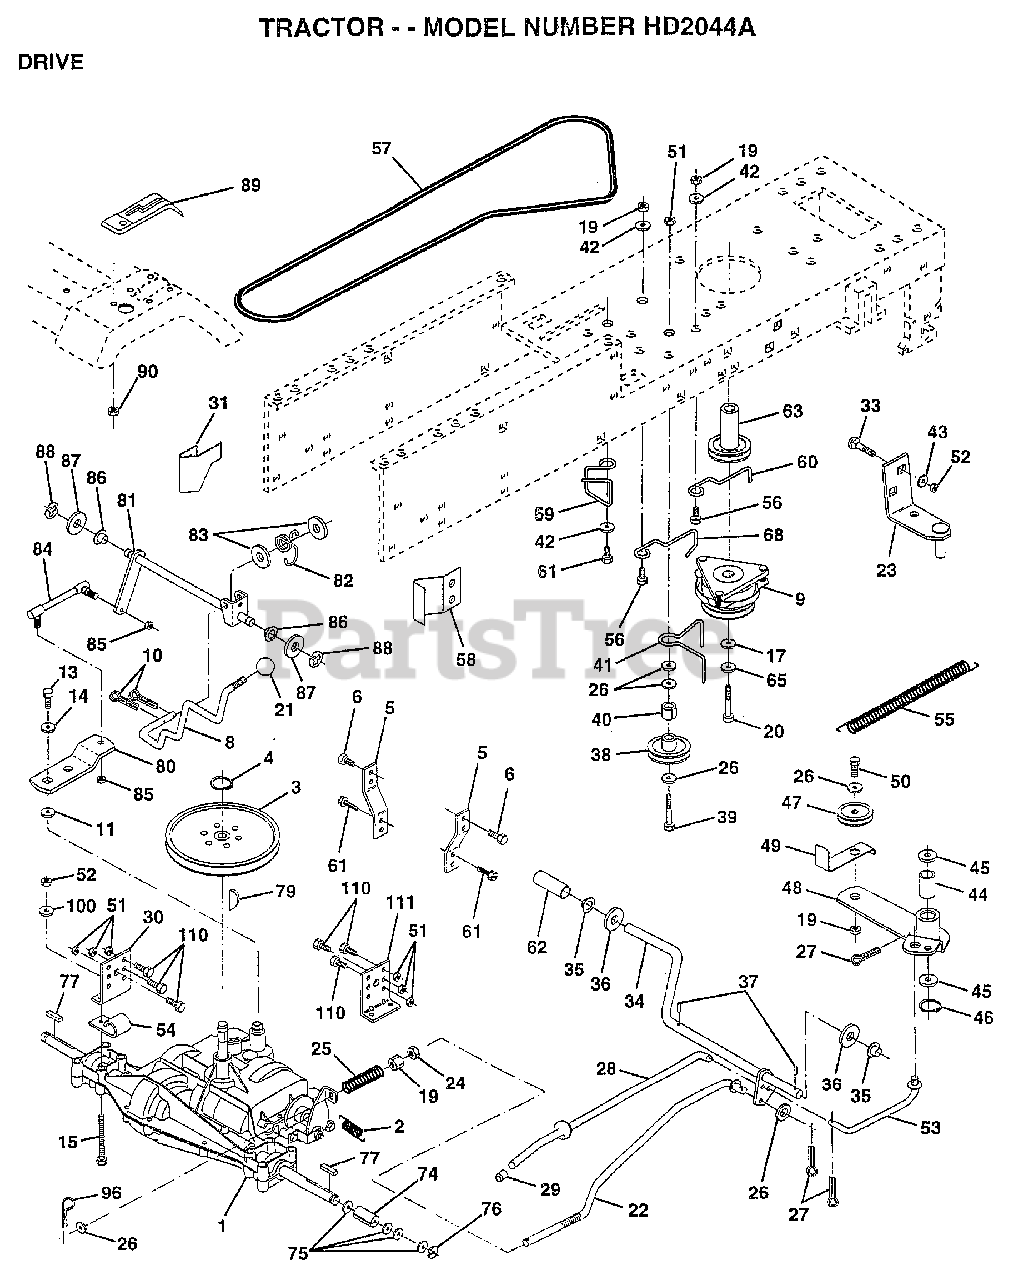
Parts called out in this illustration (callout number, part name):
1	TRANSAX. PRLES.
3	PULLEY TRANSAXLE
4	RING
5	STRAP TORQUE
6	SCREW
10	PIN COTTER 1/8
11	WASH-SHFT PLT LT
13	BOLT.1/4-28.W/PAT
14	WASHER PM
15	BOLT HEX
17	WASHER
19	NUT
21	KNOB.DUCKHEAD.1/2
22	ROD.ASM.BK.44.MWR
23	BRACKET.ASM.MTG
24	NUT
25	"SPRING,ROD BRAKE"
26	WASHER
27	COTTER PIN
28	ROD.BRAKE.PARK.LT
29	PLUNGER CAP T
30	BRKT TRANS LH
31	KEEPER BELT LH
33	BOLT
34	SHAFT.PEDAL.FOOT
35	NYLON BEARING
36	WASHER LT
38	PULLEY.IDLER.FLAT
39	BOLT
40	SPACER T
41	BELT KEEPER LT
42	WASHER
43	WASHER T
44	"LY, BEARING"
45	WASHER LT
46	KLIP RING
48	ARM IDLER
49	RETAIN BELT
53	"LINK, CLUTCH T"
54	"CLIP,INSULATOR"
55	"SPRING, RETURN LT"
57	BELT.GRDRV.94.75
58	"KEEPER,BELT RH"
59	KEEPER BELT CNTSP
60	KEEPER BELT ENGLH
61	SCREW
62	"COVER,PEDAL"
63	PULLEY ENGINE
65	LOCKWASHER
68	"KEEPER,BLT ENG LT"
74	SPACER HYT
75	WASHER
76	E RING HYT
77	SQ KEY STD
80	"ARM,SHIFT"
81	"SHAFT,SHIFTER"
82	"SPRING,TORSION"
83	WASHER
84	"ROD,TIE "
85	NUT 1/4-28
86	BUSHING
87	WASHER D
88	KLIP RING
89	CONSOLE SHIFTER
90	NUT
100	WASHER M
111	BRKT TRANS RH
